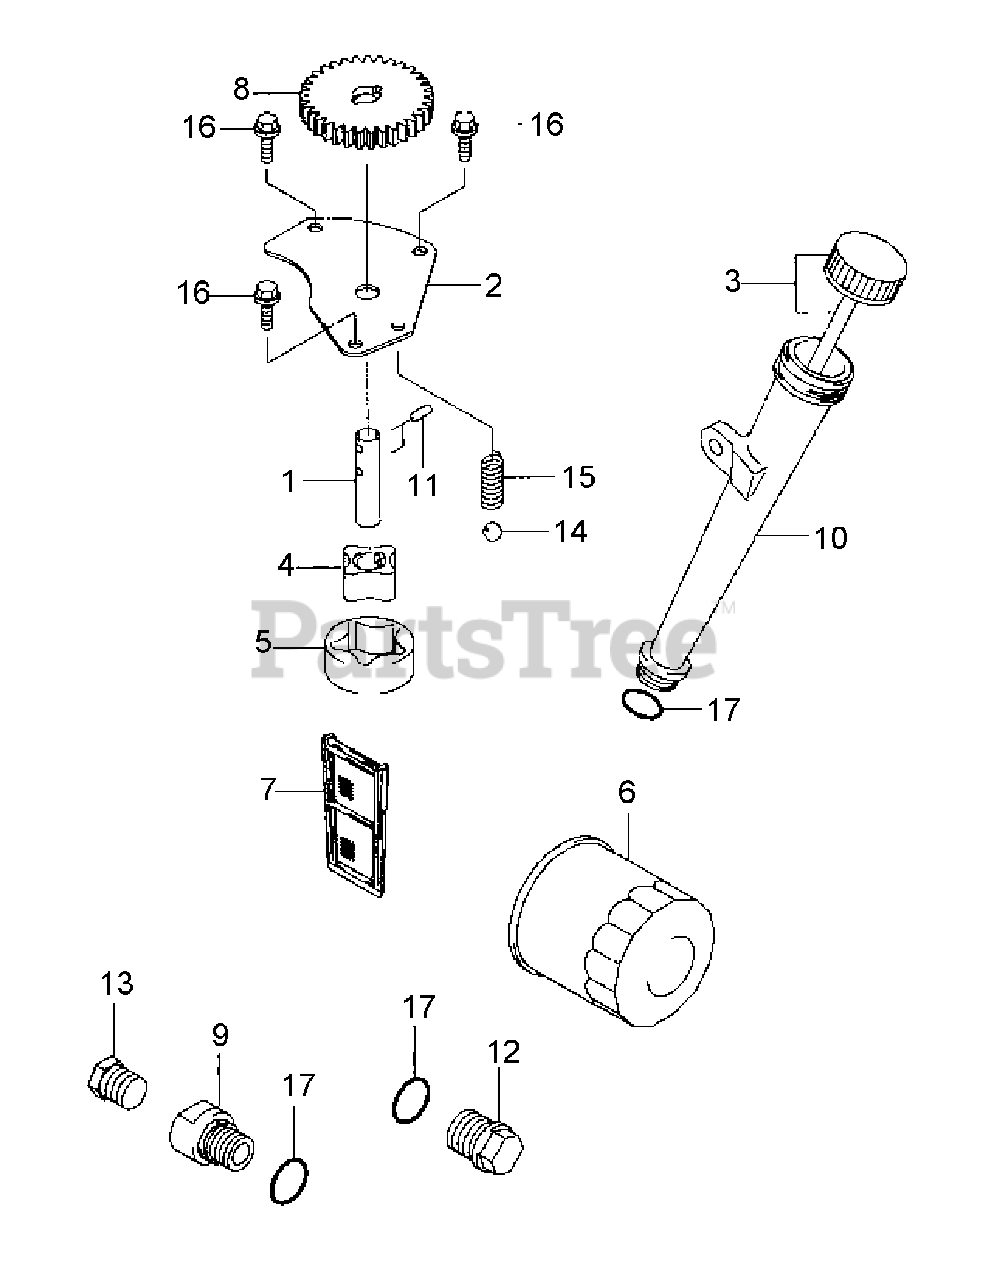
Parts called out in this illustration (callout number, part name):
1	SHAFT
4	ROTOR-PUMP, IN
5	ROTOR-PUMP, OUT
6	FILTER-OIL
7	FILTER-OIL SCREEN
9	JOINT
11	PIN
12	PLUG
13	PLUG
16	BOLT-FLANGED
17	O RING, 16MM
